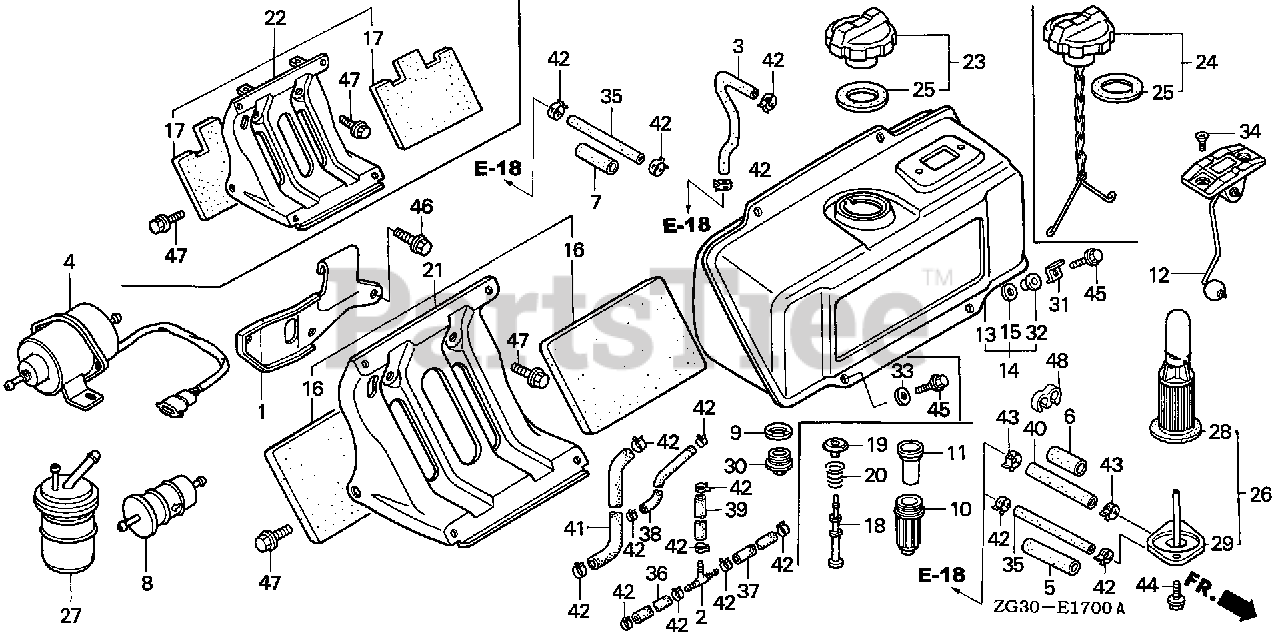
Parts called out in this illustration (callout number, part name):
1	HANGER, ENGINE
3	TUBE, FUEL
5	RUBBER, SUPPORTER (9X48)
6	RUBBER, SUPPORTER (B)
7	RUBBER, SUPPORTER (9X30)
12	GAUGE ASSY., FUEL
13	TANK, FUEL (4.5L) *R8* (BRIGHT RED)
13	TANK, FUEL *R280* (GAUGE) (POWER RED)
16	SEAT, TANK STAY
21	STAY, FUEL TANK
23	CAP, FUEL FILLER
24	CAP, FUEL FILLER
25	GASKET, FUEL FILLER CAP (39X58X3)
26	FILTER ASSY., FUEL
29	BODY, STRAINER
30	BOLT, DRAIN
31	WASHER, SPECIAL (6MM) (NOT AVAILABLE)
31	WASHER, SPECIAL (6MM)
34	SCREW, FLAT (5X10)
35	BULK HOSE, FUEL (4.5X3000) (95001-450(95001-45001-60M)
40	BULK HOSE, FUEL (8X1000) (95001-80001-(95001-80001-60M)
42	CLAMP, TUBE (D8)
43	CLAMP, TUBE (D12.5)
44	BOLT, FLANGE (6X12)
45	BOLT, FLANGE (6X14)
47	BOLT, FLANGE (8X22)
